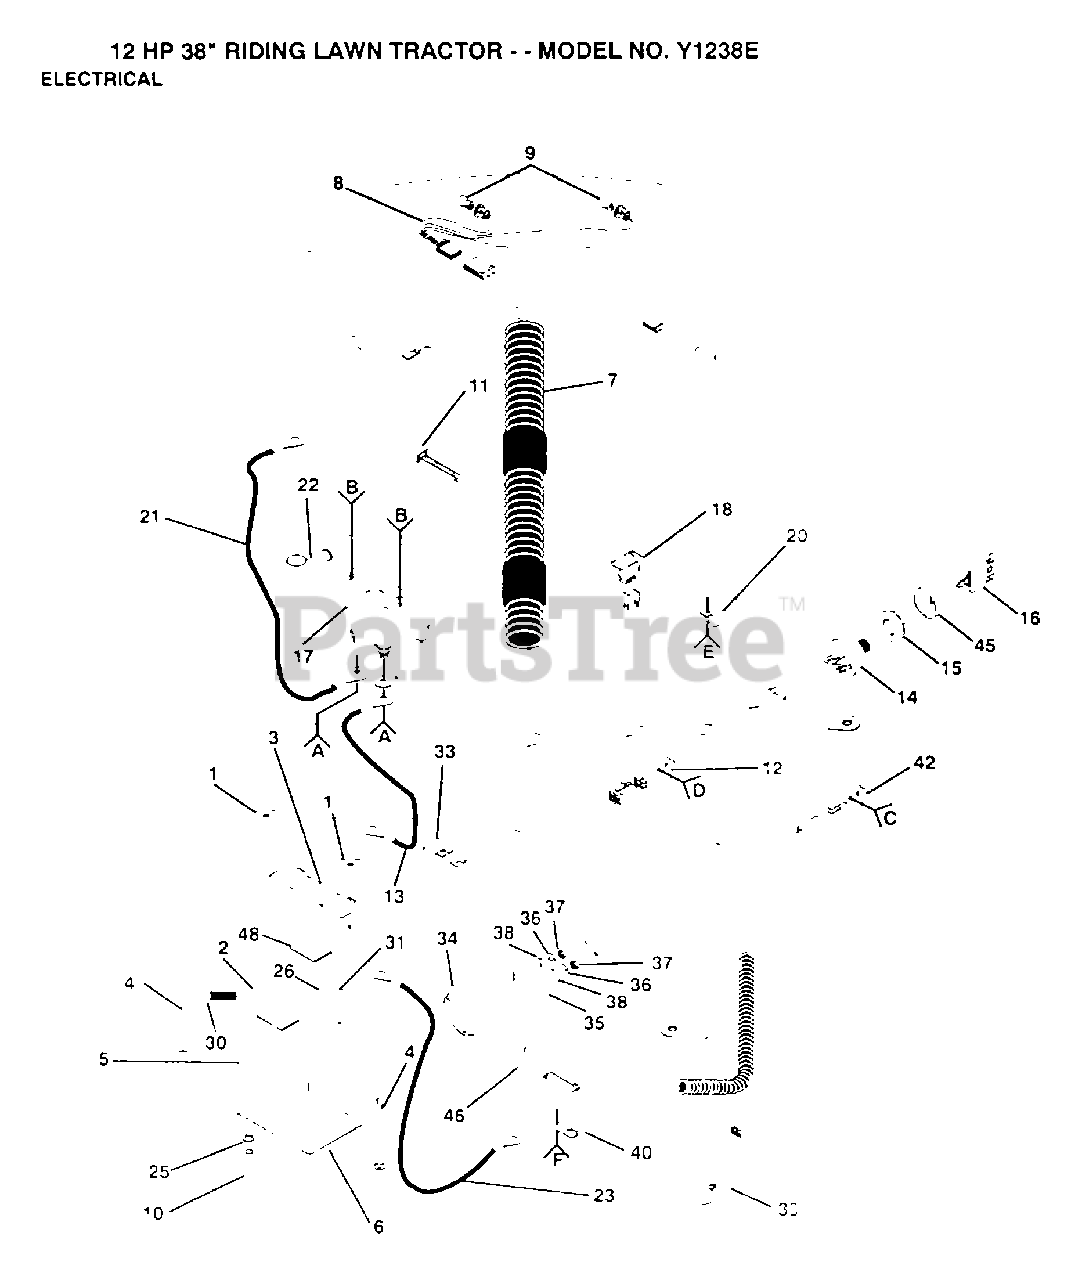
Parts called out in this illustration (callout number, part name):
2	WASHER
4	BOLT
6	"TRAY T, BATTERY"
7	IGNITION HARNESS
11	WIRE TIE
12	SWITCH INTERLOCKT
13	CABLE-BATTERY T
16	KEY
18	SWITCH LT
21	"CABLE T, BATTERY"
23	CABLE T
25	HOSE CLAMP T
26	LOCKWASHER
30	BOLT LT
33	FUSE HYT
34	AMMETER T
38	WASHER
40	CLIPT
42	SWITCH-INTER. GT
46	SWITCH SEAT
48	"CAP,BATTERY "
